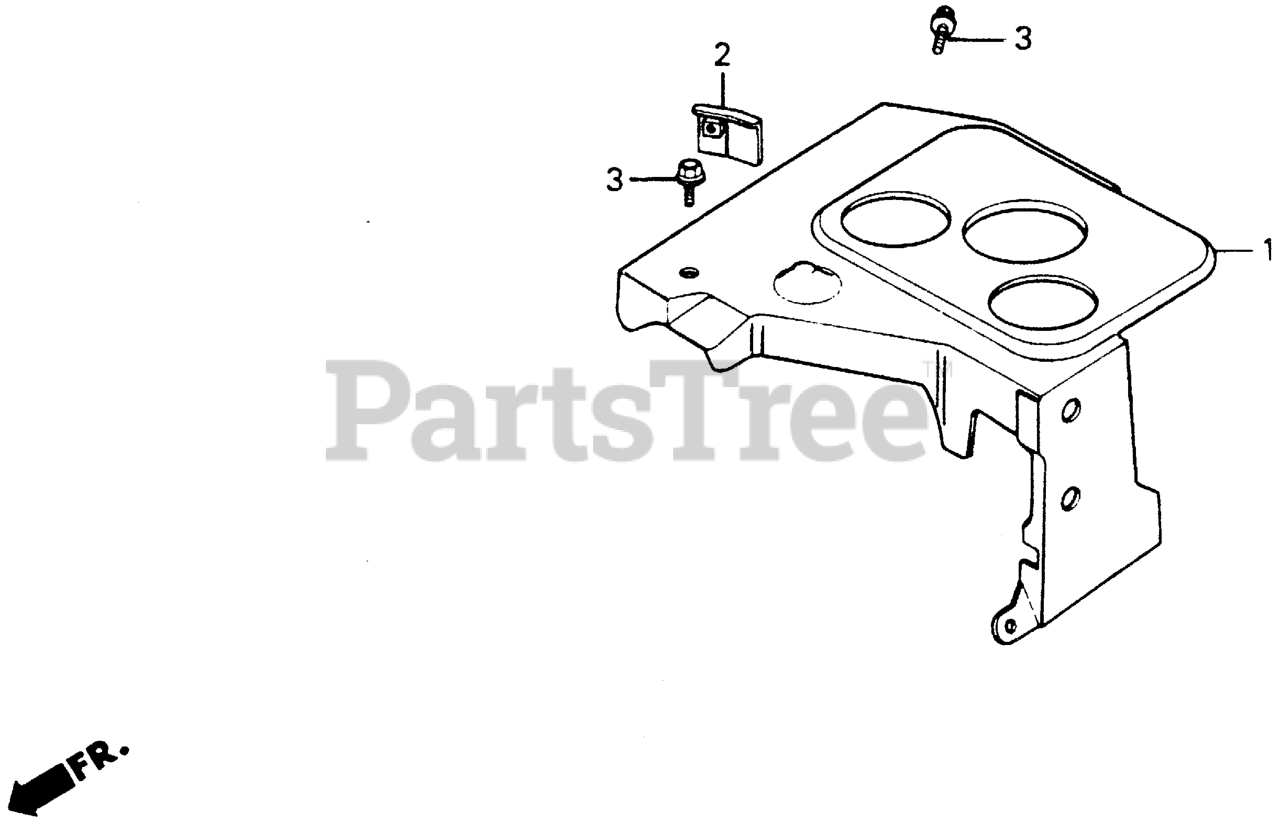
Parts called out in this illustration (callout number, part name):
1	COVER, ENG CONT
2	STOPPER, THROTTLE LEVER
3	BOLT, FLANGE (6X10)
